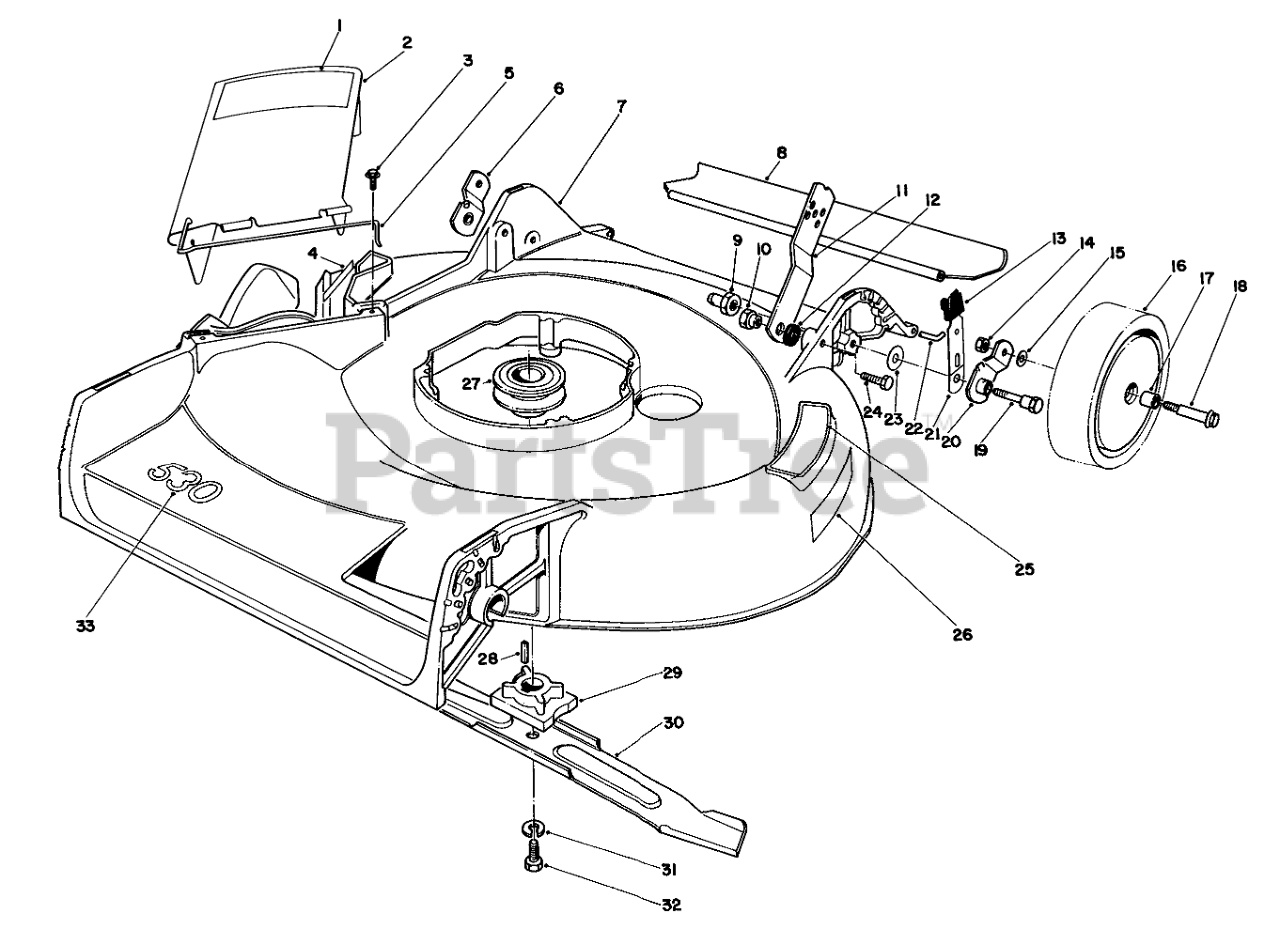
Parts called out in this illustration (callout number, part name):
1	Decal-Danger(French)
2	Deflector Assembly (Incl. Ref. #5)
3	SCREW-HWH
4	Decal-Danger
5	SPRING HINGE
6	Pivot Arm
7	Housing
8	REAR SAFETY SHIELD 21
9	HANDLE PIVOT NUT
10	HANDLE PIVOT NUT
11	Handle Latch
12	SPACER
13	KNOB-ARM
14	Nut
15	WASHER
16	Wheel & Tire Assembly (Incl. Ref. #17)
17	BUSHING
18	BOLT-WHEEL
19	5/16-18 PIVOT SCREW
20	Pivot Arm
21	SPRING ARM ASM
22	SHIELD ROD
23	WASHER-PIVOT
24	SCREW-HH
25	STEP PAD DECAL
26	Decal-Step
27	Pulley
28	Key Square
29	Blade Retainer
30	Blade
31	WASHER-LOCK
32	SCREW-HH
33	Decal-530
